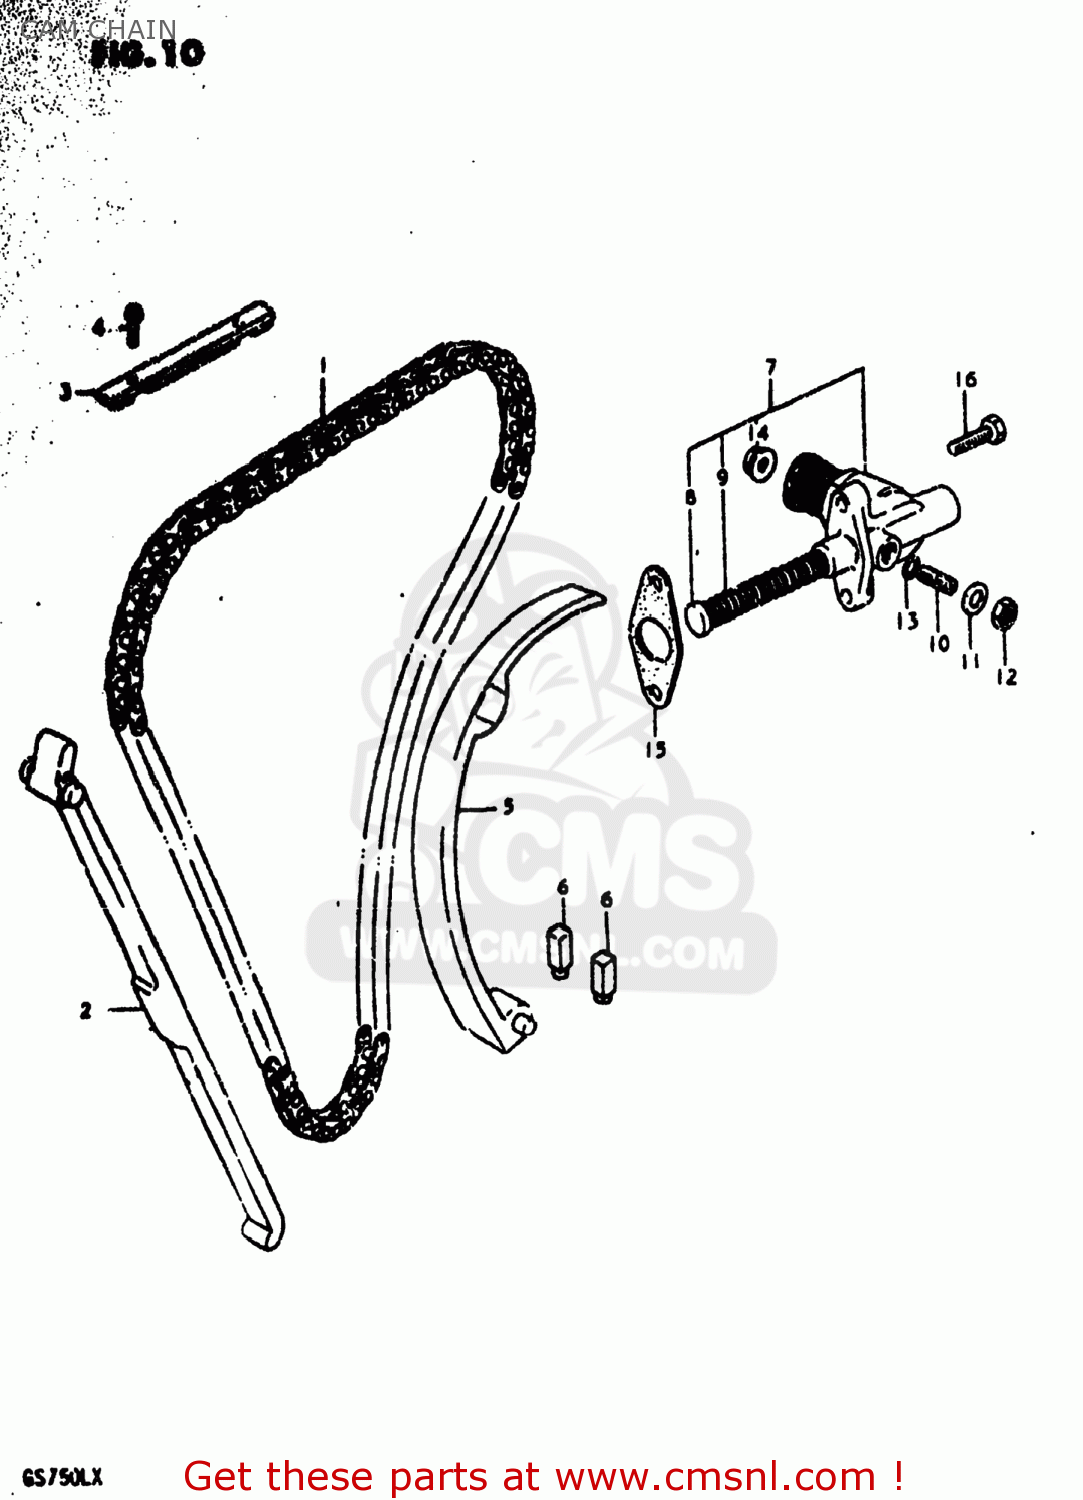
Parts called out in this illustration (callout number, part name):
1	CHAIN,CAMSHAFT DRIVE
2	GUIDE,CAM CHAIN NO.1
3	GUIDE,CAM CHAIN NO.3
4	SCREW
5	TENSIONER,CAM CHAIN
6	CUSHION,CAM CHAIN TENSIONER
7	ADJUSTER ASSEMBLY,TENSIONER
8	ROD,PUSH
9	SPRING
10	SCREW
11	WASHER
12	NUT
13	O-RING
14	NUT
15	GASKET,TENSIONER ADJUSTER (MCA)
16	SCREW (6X25)
